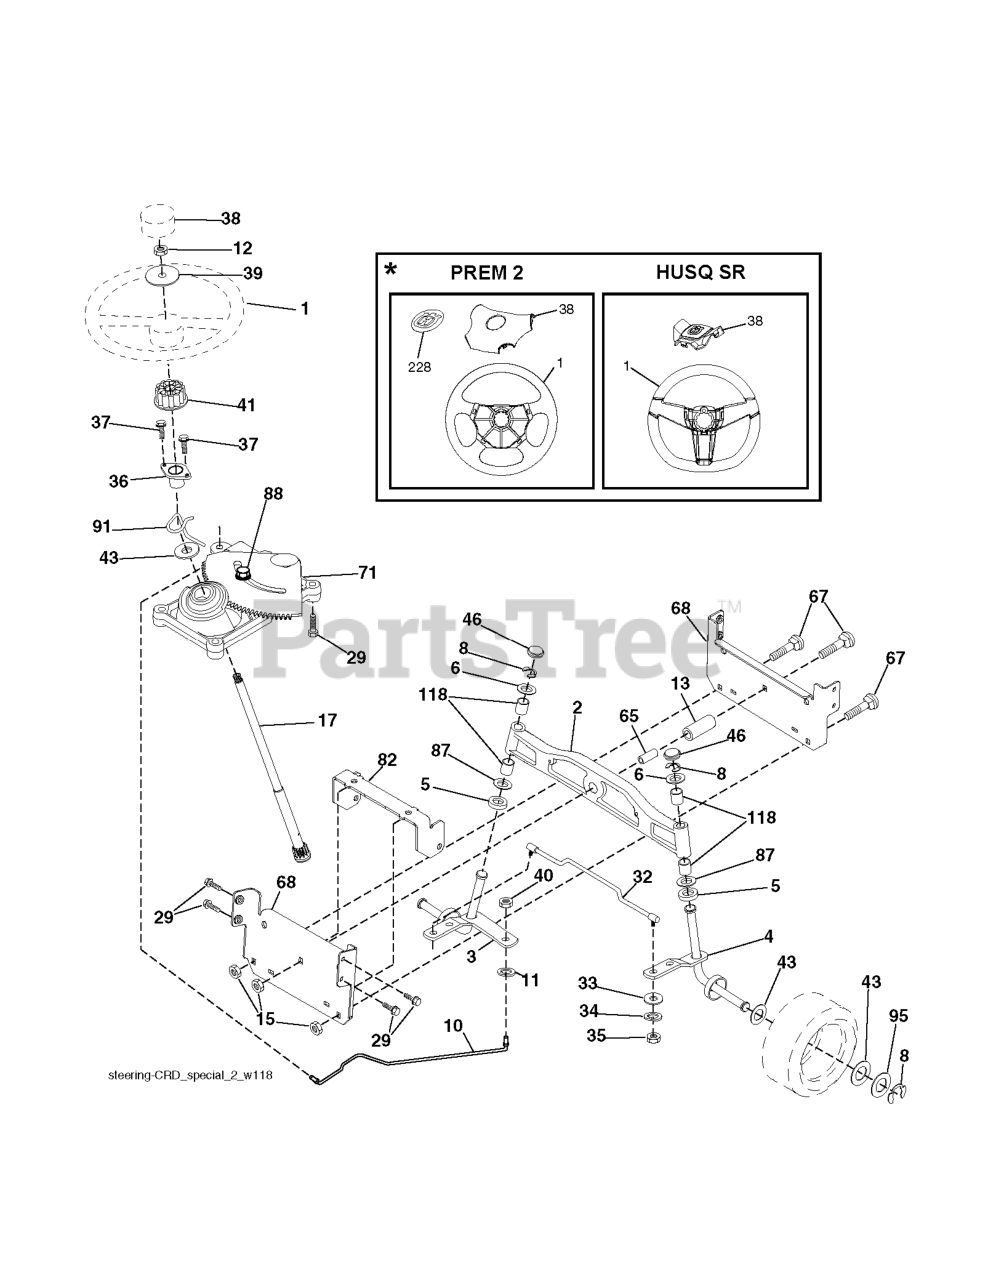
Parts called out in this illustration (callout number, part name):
1	RP WHEEL.STEER.HUSQ.PREM.OVMLD
2	AXLE ASSY FRONT
3	SPINDLE.ASM.LH.15"TIRES
4	SPINDLE.ASM.RH.15"TIRES
5	THRUST WASHER
10	DRAGLINK.15".TIRES.2001
11	WASHER, LOCK 3/8
12	NUT.HEX.1/2-20
13	TUBE, PIVOT AXLE
15	NUT
17	SHAFT ASM STRG
29	SCREW, 3/8-16X3/4
33	WASHER M
34	WASHER.LOCK.HVY.HLCL.SPR.5/16
35	NUT, CROWNLOCK
36	BUSHING, STRG. BLK
37	SCREW.TT.#10-32X.5.3/8.FLANGE
38	RP INSERT.CAP.WHL.STRG.HUSQ.
39	WASHER 9/16"ID, 2 3/8"OD
40	NUT CROWNLOCK 3/8-24
41	ADAPTER, WHEEL STNG..
46	CAP.SPINDLE.BLACK
65	SPACER BRACE AXLE
67	BOLT CARRIAGE
68	BRACE.AXLE.15"TIRES
71	STEERING ASM
82	BRACKET.SUSP.CHASSIS.FRONT.15
87	WASHER, FLAT .781 X 1 1/2"
88	BOLT, SHOULDER 7/16-20
91	CLIP.STEERING
95	WASHER.HARDENED
118	BUSHING, AXLE CAST
228	DECAL.WHEEL.STRG.LGN.H
